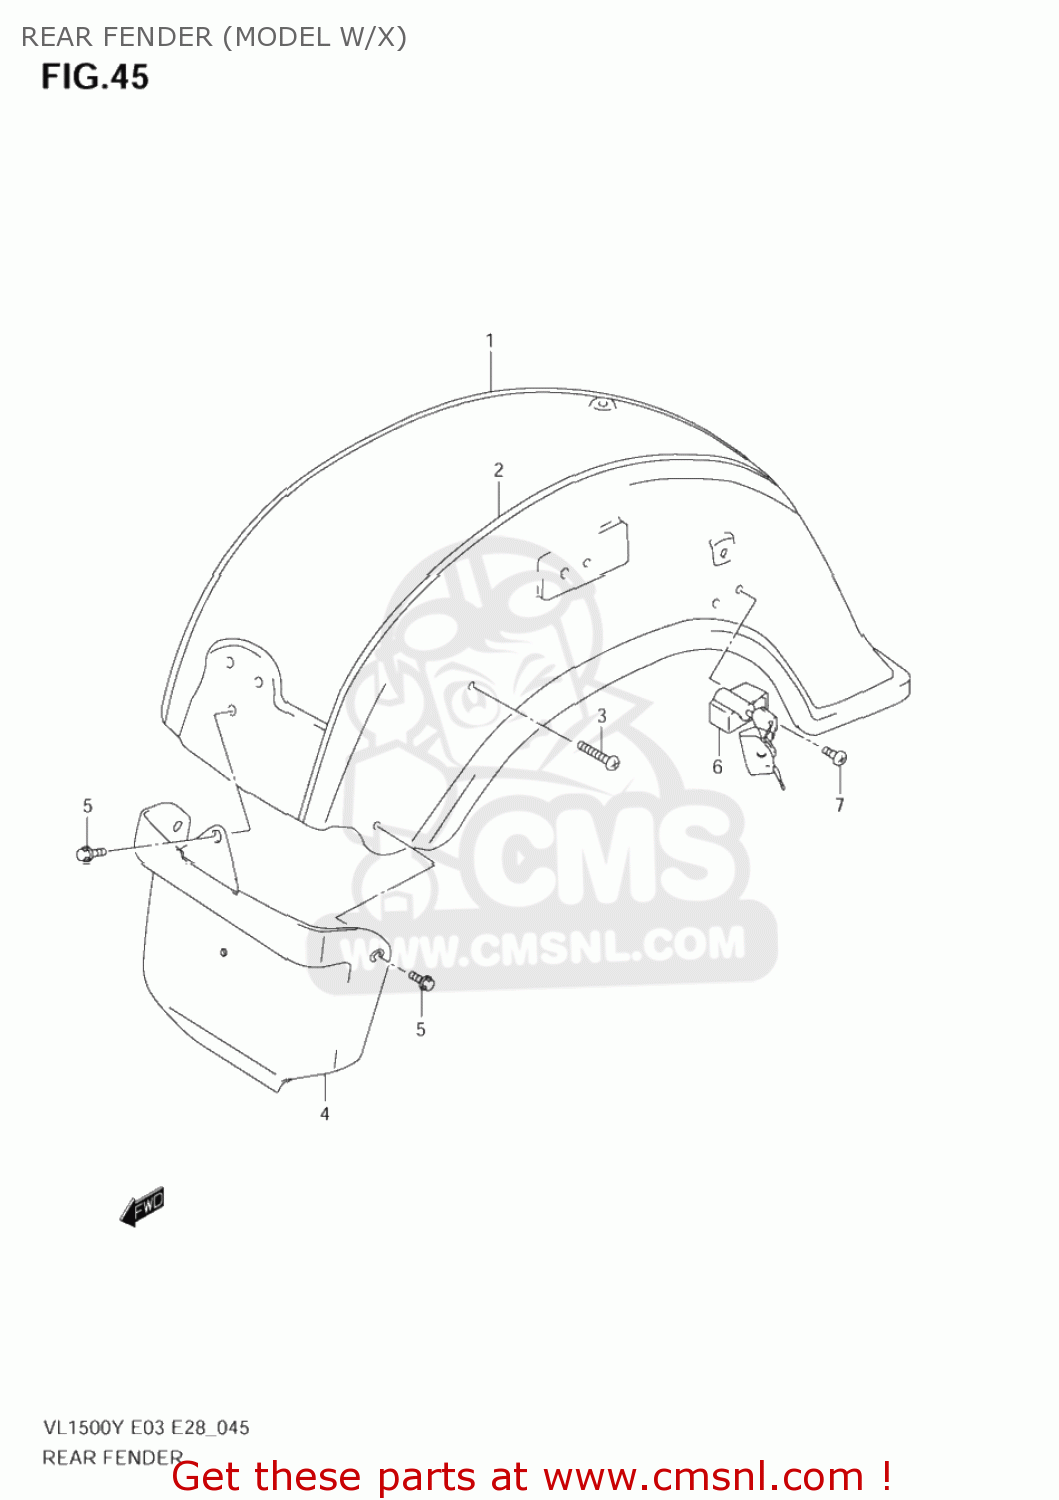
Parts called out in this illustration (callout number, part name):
1	FENDER,RR
2	TAPE SET,RR FENDER
3	BOLT,REAR FENDER
4	MUDGUARD,RR FENDER FR
5	BOLT(6X16)
6	LOCK SET,HELMET
7	SCREW(6X14)
